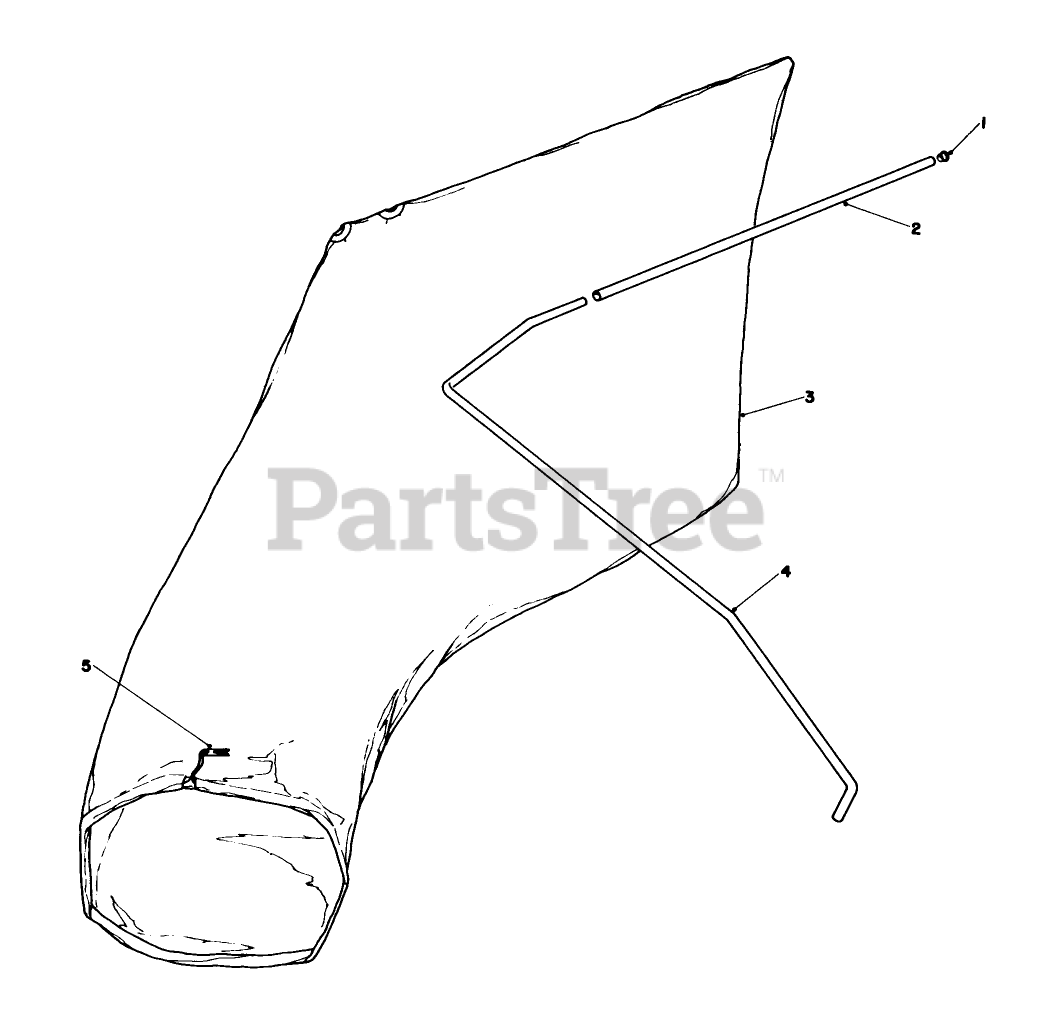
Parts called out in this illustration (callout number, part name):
2	BAG HANGER TUBE
3	Bag (Incl. Ref. #5)
4	Hanger Rod
5	BAG CORD FASTENER
